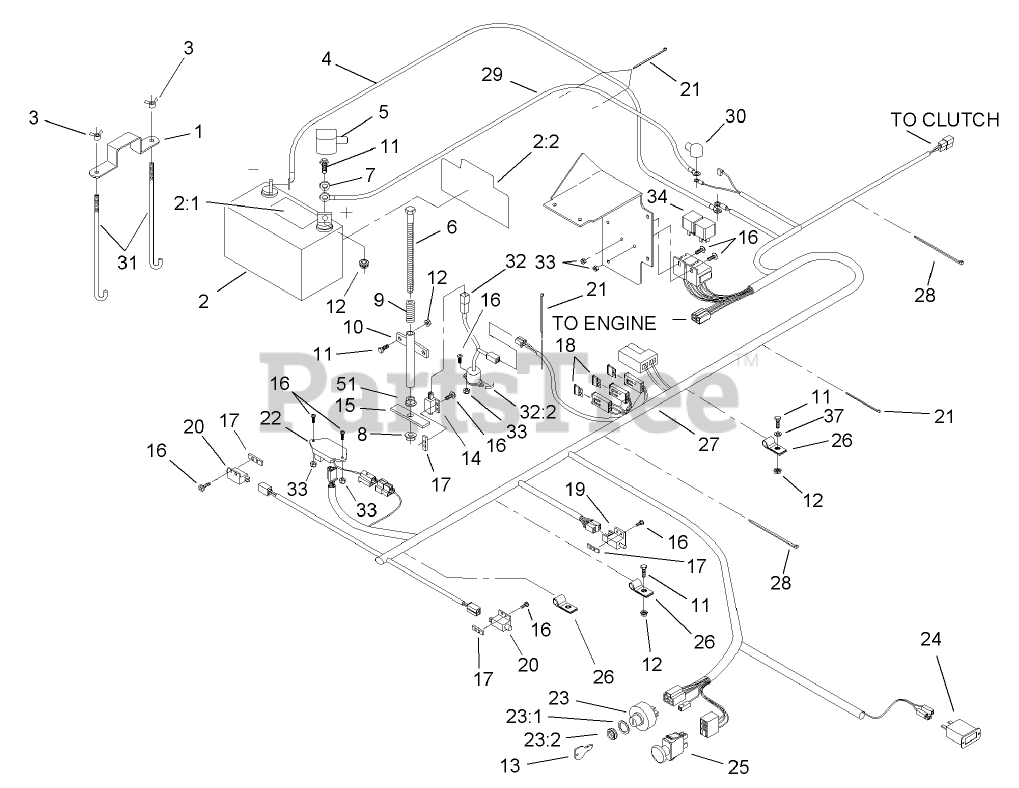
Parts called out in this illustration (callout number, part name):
1	STRAP-HOLDDOWN
2	BATTERY
2:1	Decal-Battery
2:2	Decal-Battery
3	WINGNUT
4	WIRE-GROUND
5	INSULATOR-BATTERY
6	SCREW-HH
7	WASHER-FLAT
8	NUT-LOCK, NI
9	SPRING-SWITCH, SEAT
10	MOUNT-SPRING, SEAT
11	SCREW-HH
12	NUT-HF
13	KEY-IGNITION
14	SWITCH-CLOSED, NORMALLY
15	PLATE-SWITCH, SEAT
16	SCREW-PPH
17	PLATE-TAPPED
18	FUSE-BLADE TYPE, 20 AMP
19	SWITCH
20	SWITCH-OPEN, NORMALLY
21	TIE-CABLE
22	MODULE-DELAY, SEAT
23	Key Switch ASM
23:1	WASHER-TOOTH, INTERNAL
23:2	NUT-HH
24	METER-HOUR
25	SWITCH-DELTA
26	CLIP-LOOM
27	Harness-Wire
28	TIE-PLASTIC
29	WIRE-STARTER
30	INSULATOR-SOLENOID
31	BOLT-HOLDDOWN
32	TILT SWITCH ASM
32:2	DECAL-SWITCH, MERCURY
33	NUT-LOCK, NI
37	WASHER-FLAT
51	NUT-HEX
